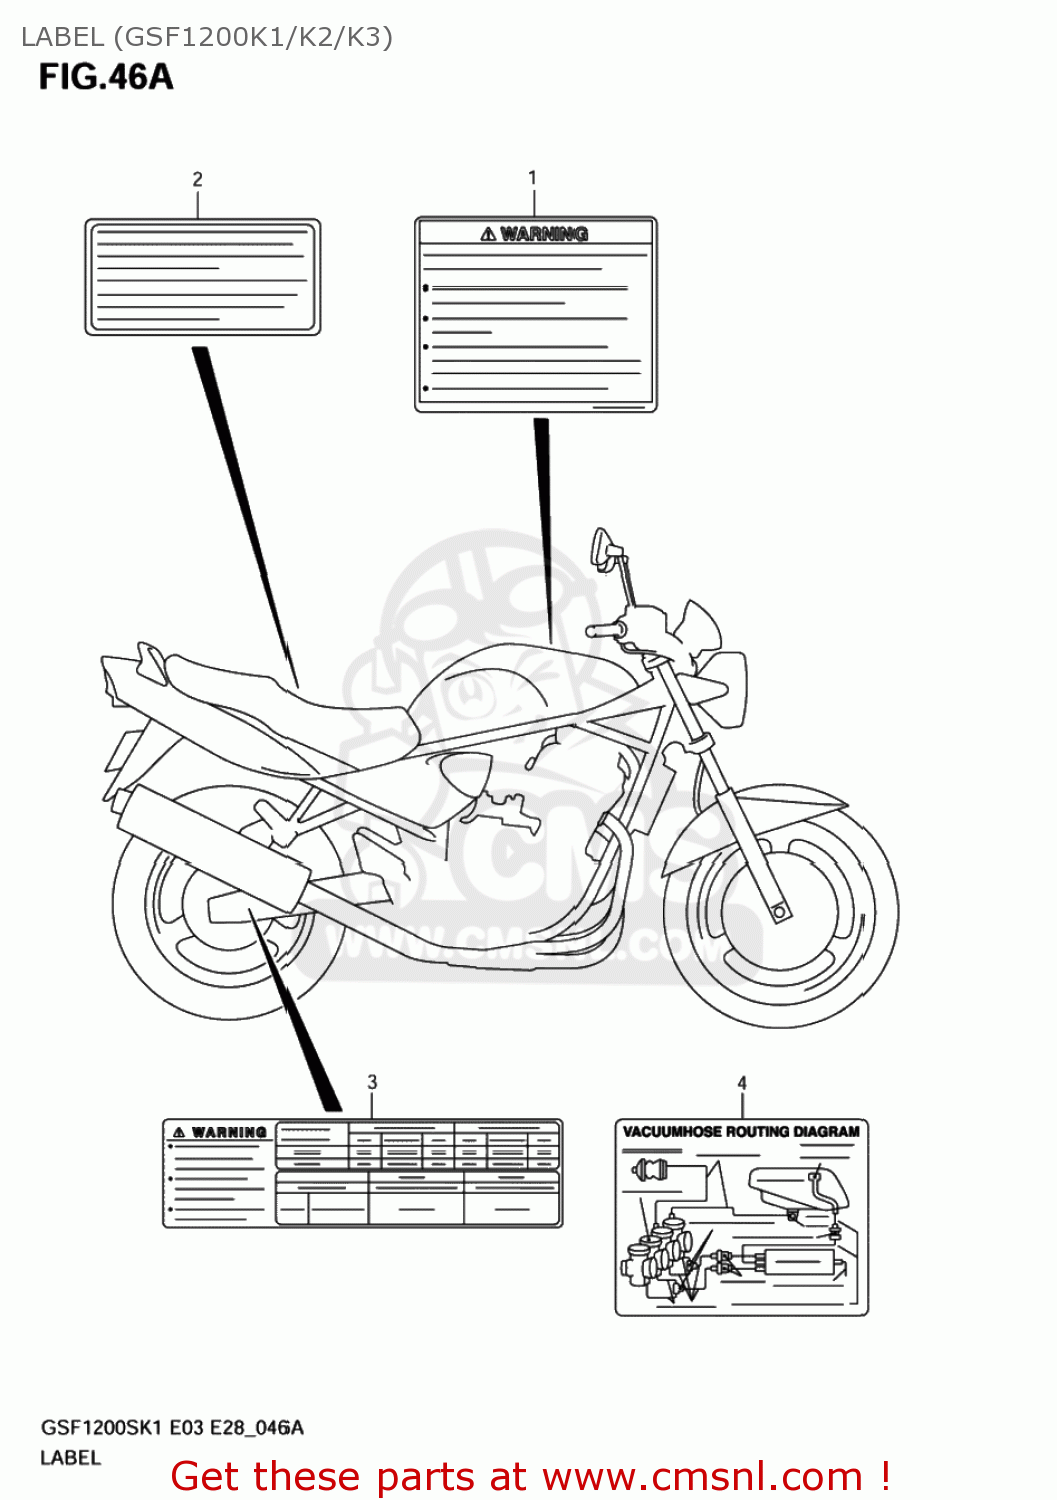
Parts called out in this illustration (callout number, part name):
1	LABEL,GENERAL WARNING
2	LABEL,MANUAL NOTICE
3	LABEL, TIRE INFORMATION
4	LABEL,VACUUM HOSE ROUTING
5	MANUAL,SAFETY
